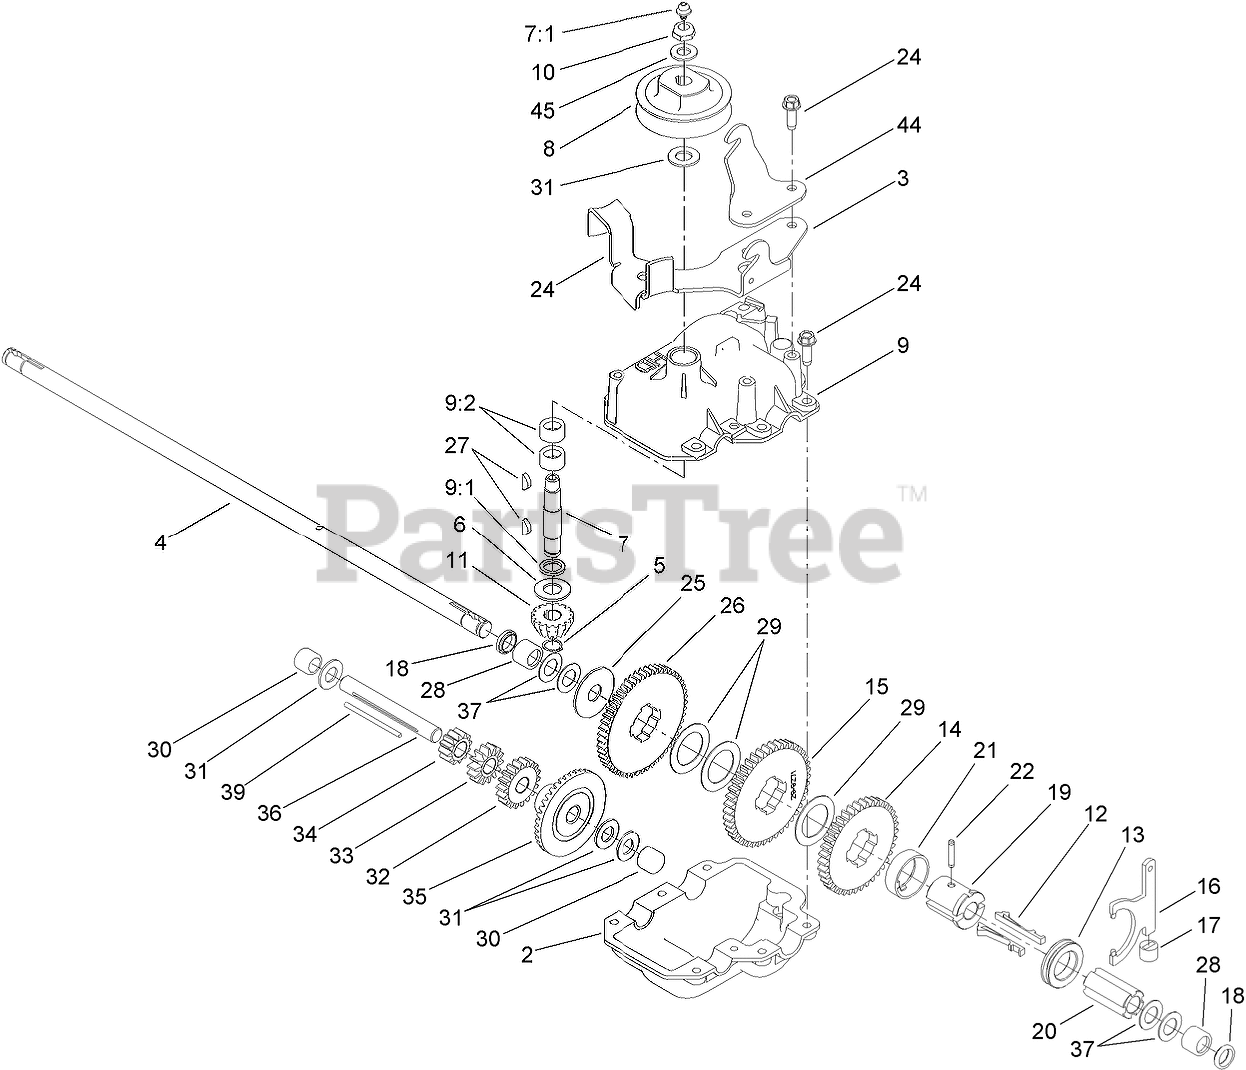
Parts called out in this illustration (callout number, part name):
2	Gear Case-Lower
3	BRACKET-GUIDE, BELT
4	SHAFT-OUTPUT
5	RING-RETAINING
6	WASHER-THRUST
7	INPUT SHAFT ASM
7:1	FITTING-GREASE, ZERK
8	PULLEY
9	UPPER GEARCASE ASM
9:2	BEARING-NEEDLE
10	NUT-HEX
11	PINION-BEVEL
12	KEY-SHIFT
13	COLLAR-SHIFT
14	GEAR-38T
15	GEAR-42T
16	YOKE-SHIFT
17	BUSHING-YOKE
18	SEAL-OIL
19	SLEEVE-GEAR
20	SLEEVE
21	RETAINER-KEY
22	PIN-GROOVE
24	SCREW-HWHTF
25	WASHER
27	KEY-WOODRUFF
28	BEARING-CAGED NEEDLE ROLLER
29	WASHER
30	BEARING-NEEDLE, CLOSED
31	WASHER-THRUST
32	GEAR-18T
33	GEAR-14T
34	GEAR-12T
35	GEAR-BEVEL
36	SHAFT-INTERMEDIATE
37	WASHER-PLAIN
44	BRACKET-ENGAGE, TRACTION
45	WASHER-FLAT
